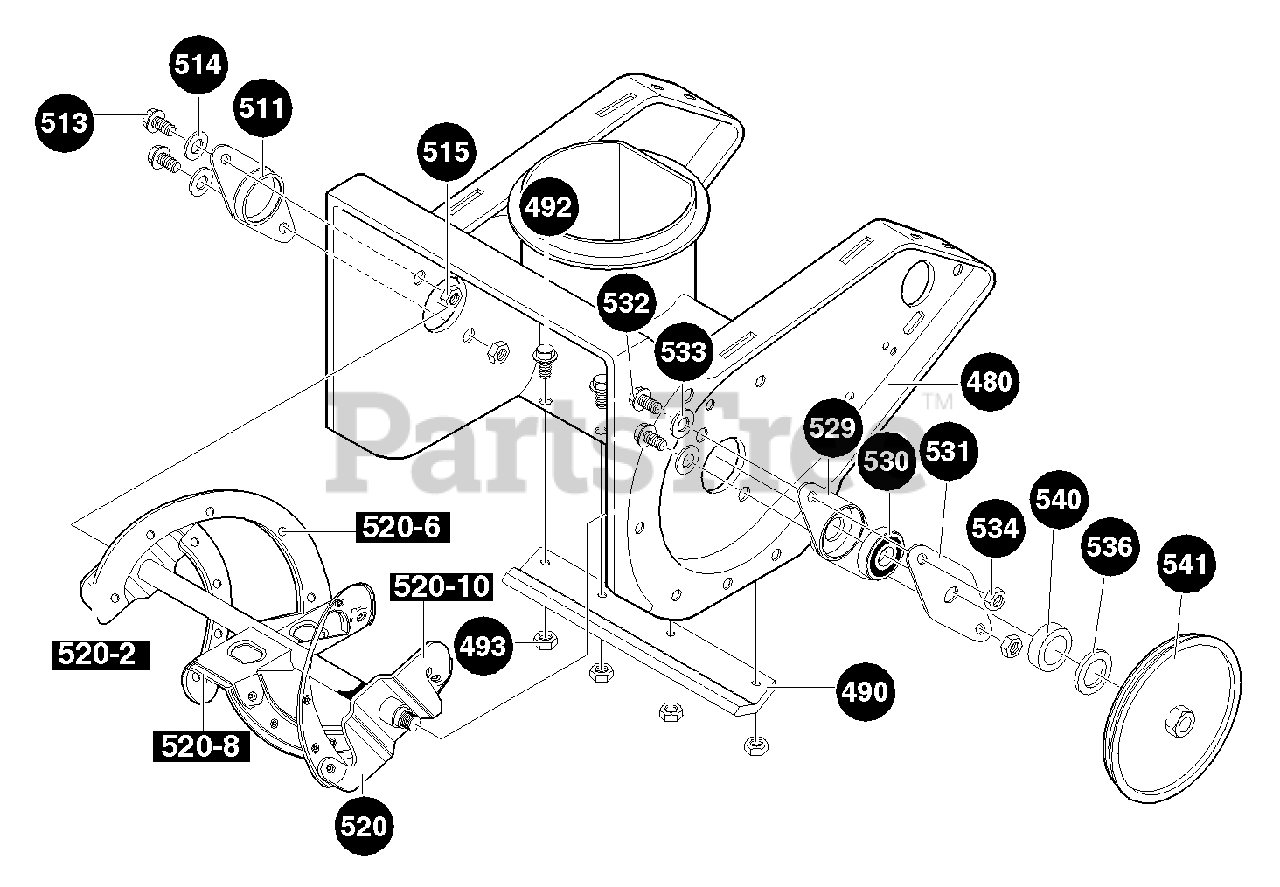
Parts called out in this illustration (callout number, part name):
480	HOUSING, AUGER
490	SCRAPER BLADE
492	SCREW, 1/4-20 X .63
493	NUT, 1/4-20 MAC-LOCK
511	BEARING, FLANGED
513	SCREW, 1/4-20 X .88
514	FLATWASHER .281 X .63 X .065
515	NUT, 1/4-20 MAC-LOCK
520	AUGER, ASSY COMP
529	BEARING RETAINER
530	BALL BEARING
531	PLATE, RETAINER BRNG
532	SCREW 1/4-20 X .75
533	FLATWASHER .281 X .63 X .065
534	NUT, 1/4-20 RGHXCTRLK
536	FLATWASHER .640 X 1.25 X .06
540	SPACER, SLEV
541	PULLEY, POLY V
5202	BLADE, AUGER
5206	RIVET, OVSET
5208	AUGER, ASSY COMP
52010	AUGER & BLADE SUPP.
